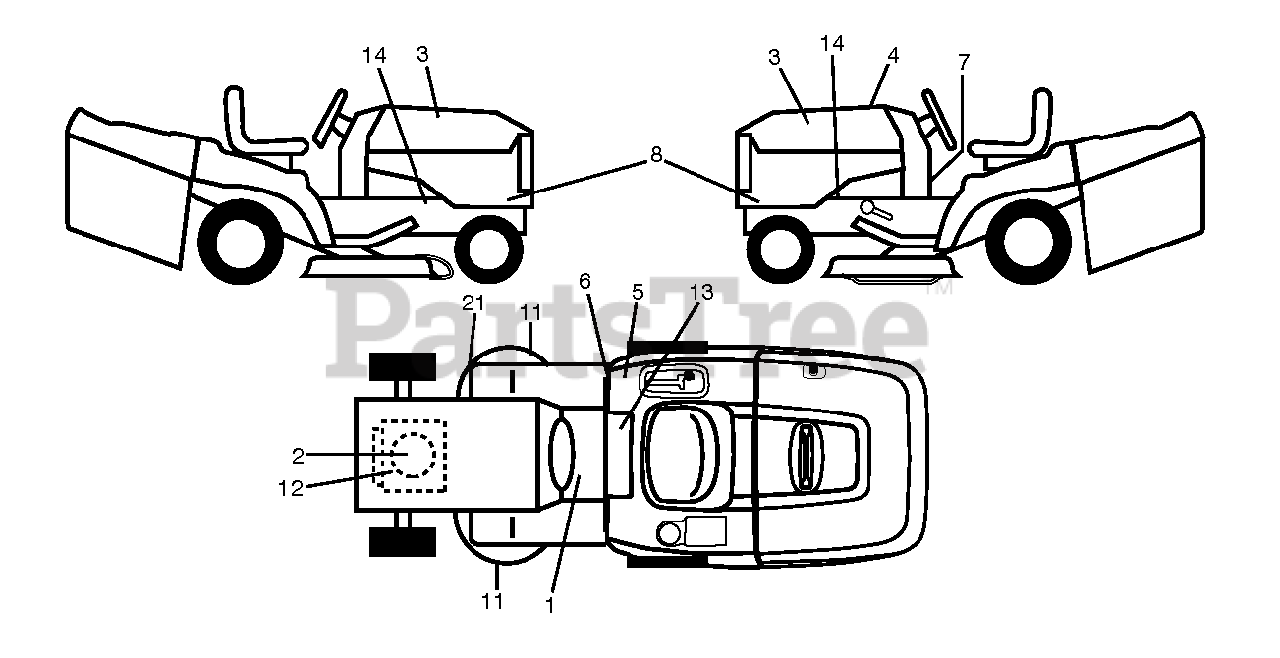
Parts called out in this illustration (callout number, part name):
2	DECAL
3	RP.DECAL.BADGE.170MM.TEXTLOGO
5	DECAL
6	DECAL 80 DBA
11	DECAL.INTERNATIONL.CUTFINGER
12	DECAL.ENG.BS26HP.ENDUR*SUBS/2*
13	DECAL
21	DECAL DECAL V-BELT 97 CM CRD
